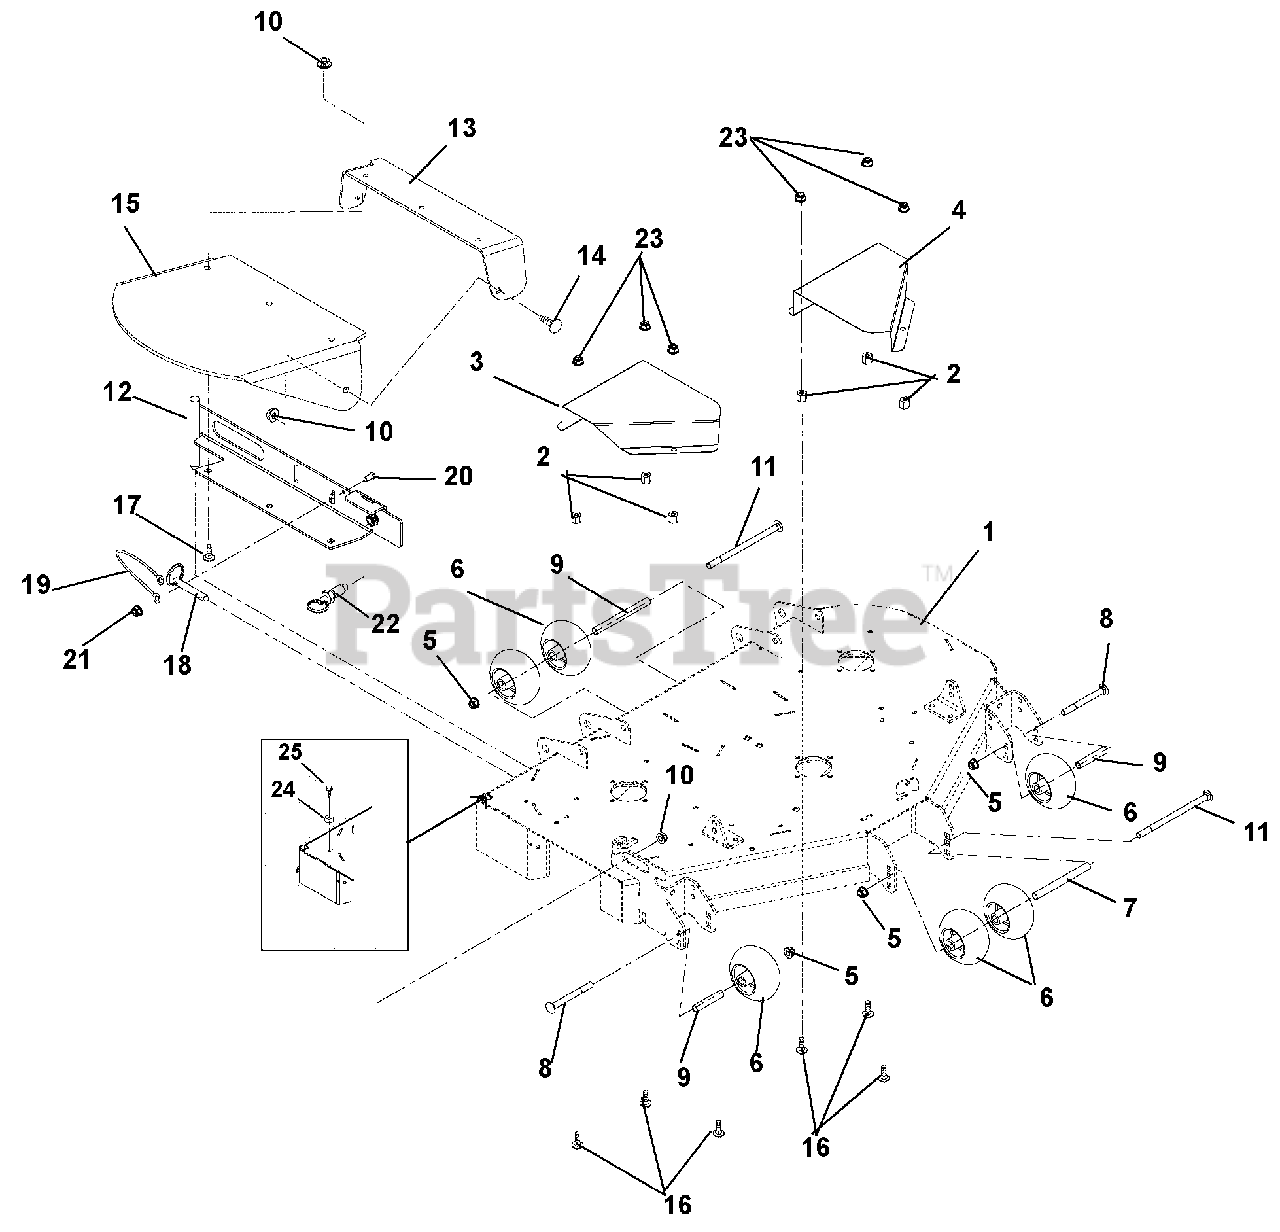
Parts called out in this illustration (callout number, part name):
1	44" Side Discharge Deck Weldment
2	Nut, Heavy Hex .38-16
3	Guard, 44-52 RH Spindle Sheave
4	Guard, 44-52 LH Spindle Sheave
5	Nut .50-13 Nyloc Flange
6	Anti-Scalp Wheel
8	Bolt, Round Head Square Neck .50-13 x 5.00
9	Spacer, .510 x .625 x 3.35
10	Nut, .38-16 Nyloc Flange
11	Bolt, Round Head Square Neck .50-13 x 8.50
12	Weldment, Discharge Chute Support
13	Rubber Discharge Chute Support
14	Bolt, Round Head Square Neck .38-16 x 1.00 Grade 5
15	Chute, Rubber Discharge
16	Bolt, Hex Head .38-16 x 1.25 Grade 5
17	Bolt, Round Head Square Neck .38-16 x 1.25 Grade 5
18	Pin, Spring Ball .375 x 1.50
19	Cable, 6.0 Lanyard
20	Bolt, Hex .25-20 x .75
21	Nut, Locking Top Flange .25-20
22	Pull Pin
23	Nut, Flange .375-16
24	BUMPER, RECESSED 1.50 X .63 W/ .31
25	SCREW, TAPPING .31-18 X .75 HEX WASHER HEAD THREAD
